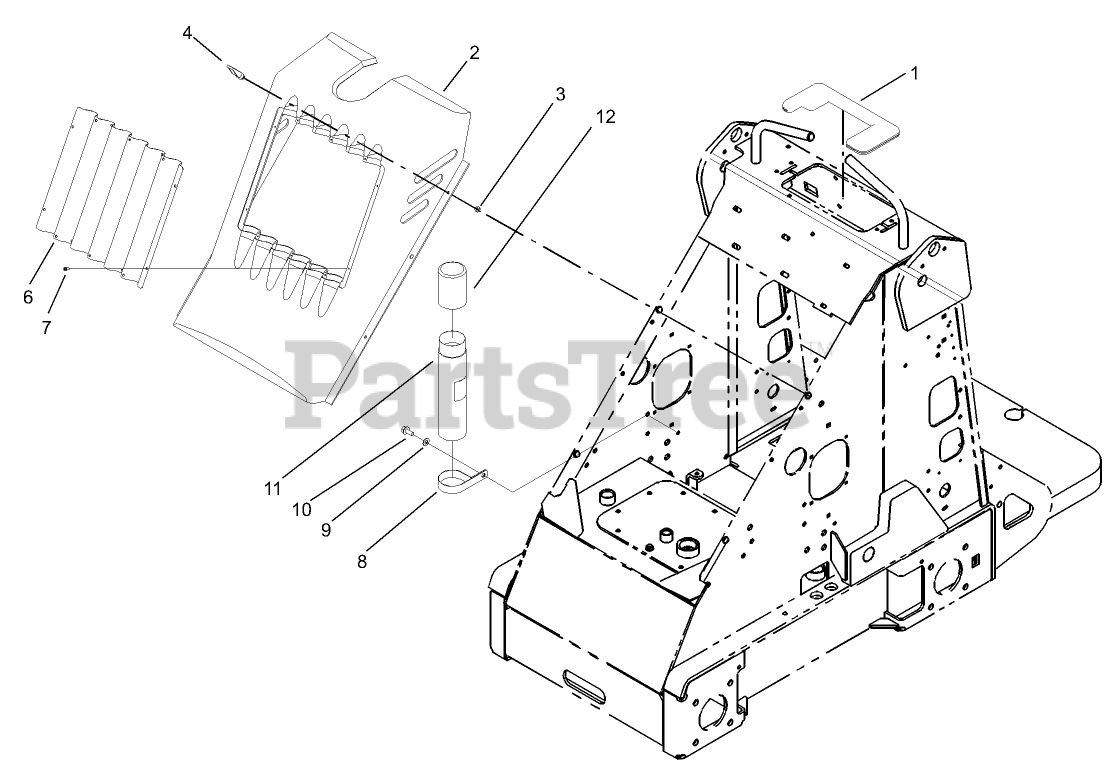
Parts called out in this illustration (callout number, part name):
1	COVER-VALVE
2	COVER-HOOD
3	WASHER
4	LATCH-SWELL
6	GRILLE-SCREEN
7	SCREW-PPH
8	CLAMP-R
9	WASHER-PLAIN
10	SCREW-HWHTF
11	TUBE-MANUAL
12	CAP-HOUSING
